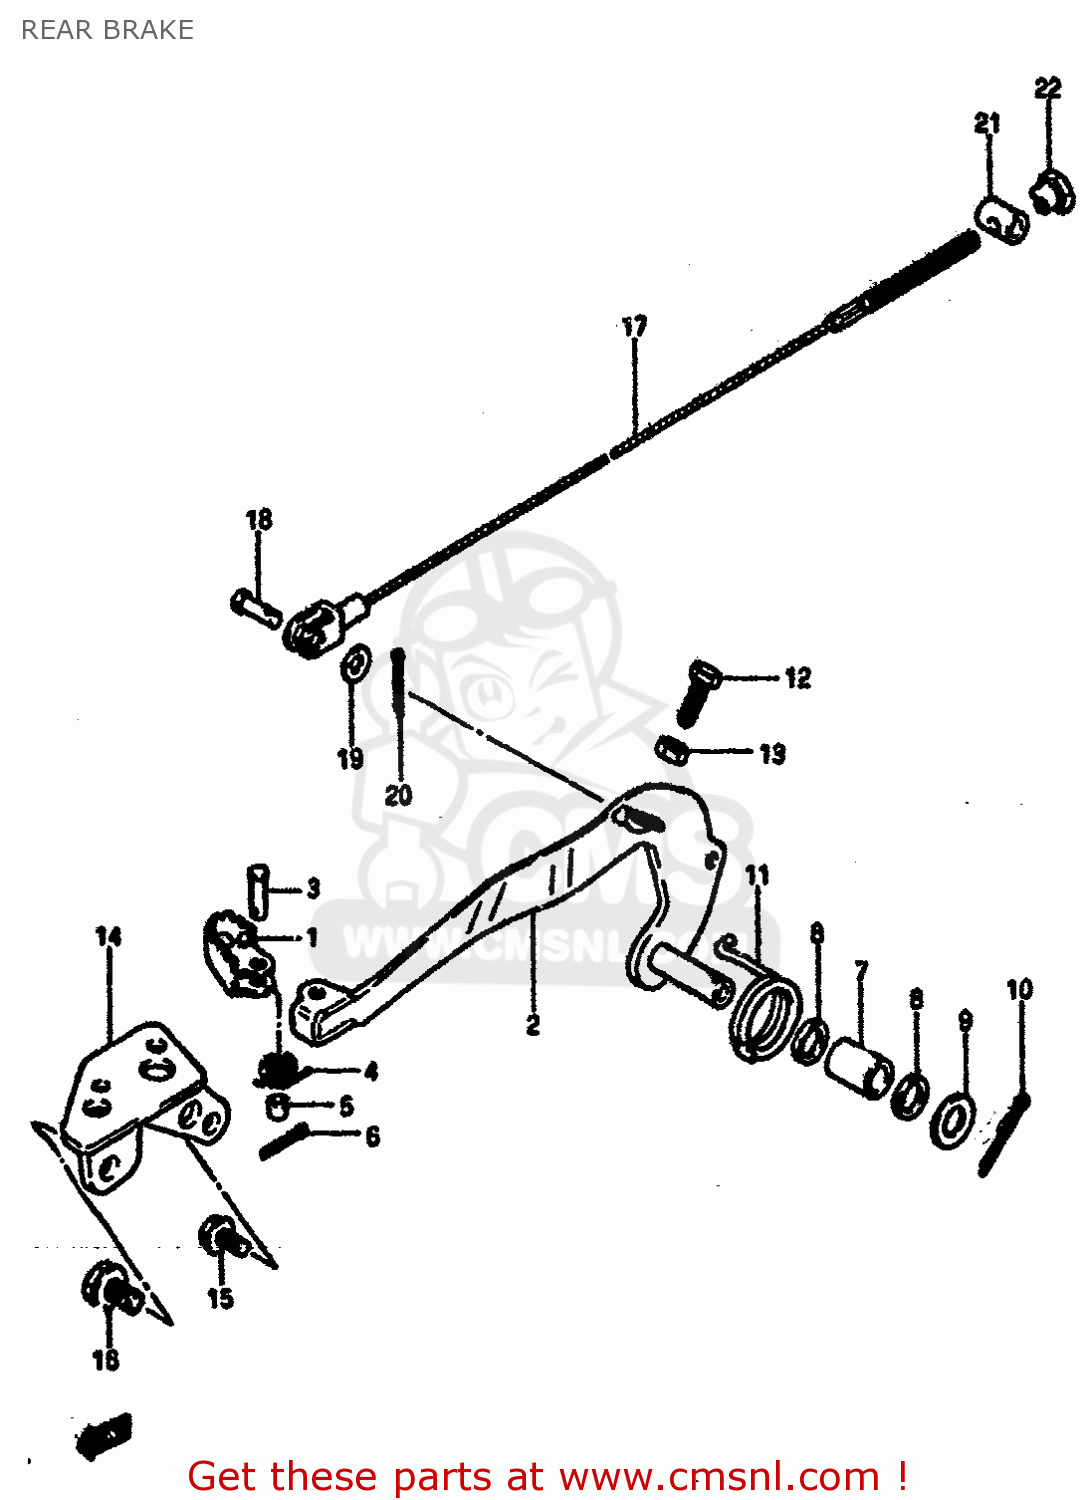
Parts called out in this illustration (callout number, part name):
1	PEDAL,BRAKE
2	ARM,BRAKE PEDAL
3	PIN
4	SPRING
5	SPACER(9.2X9X6.5)
6	PIN
7	BUSHING
8	O RING(D:2.2,ID:11.8)
9	WASHER
10	PIN 30X20
11	SPRING
12	SCREW(6X23)
13	NUT
14	PROTECTOR,BRAKE
15	BOLT
16	BOLT 8X12
17	CABLE ASSEMBLY,REAR BRAKE
18	PIN(L:17.5)
19	WASHER
20	PIN 20X20
21	PIN
22	NUT (6MM)
